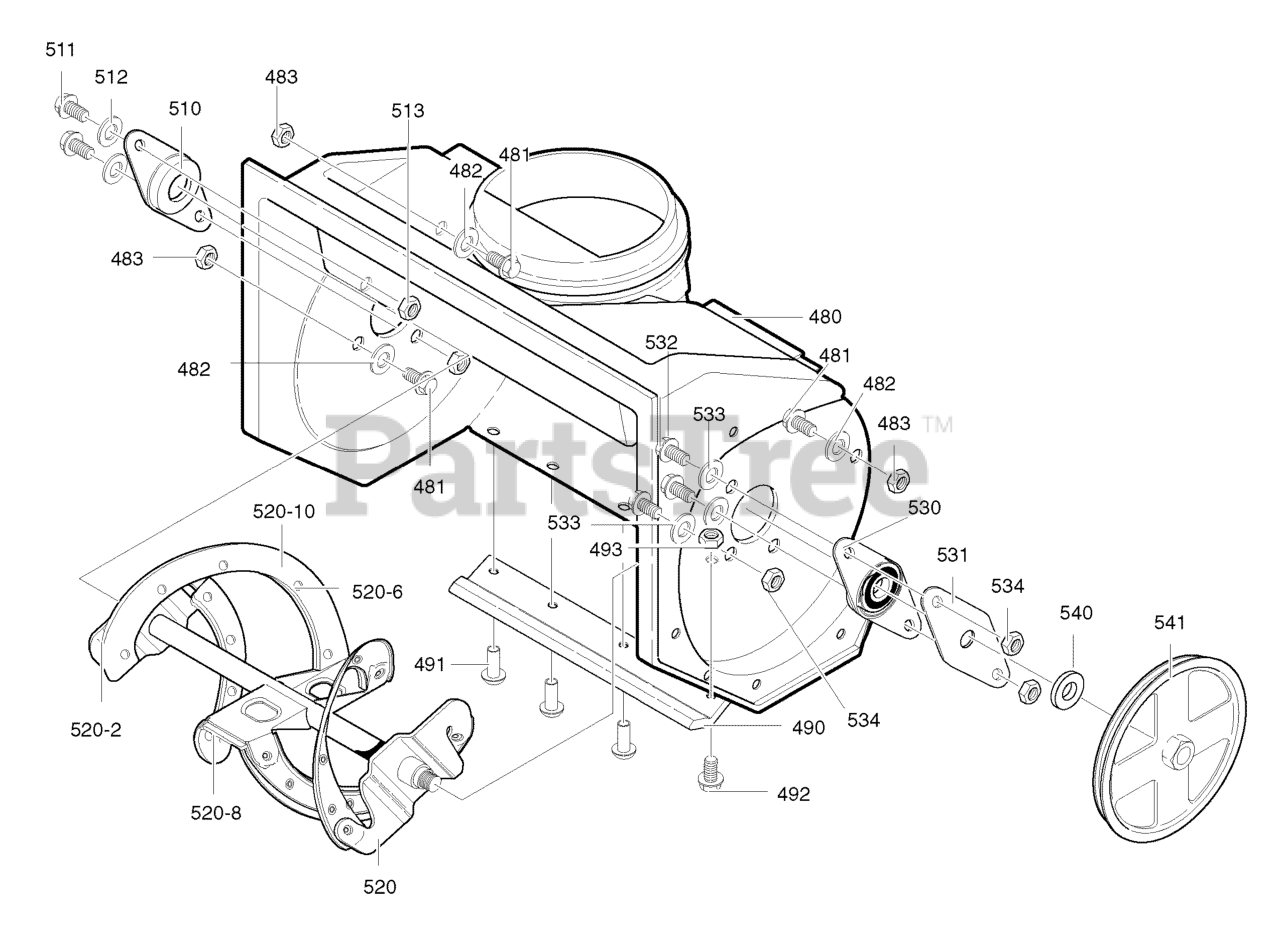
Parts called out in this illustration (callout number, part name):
480	HOUSING, ASSEMBLY
481	SCREW, 1/4-20 X .75
482	WASHER, FLAT .281 X .63 X .065
483	NUT, HEX 1/4-20 YZ
490	BLADE, SCRAPER
491	RIVET, OFFSET
492	SCREW, 1/4-20 X .75
493	NUT, 1/4-20 YZ
510	BEARING, FLANGE
511	SCREW, 1/4-20 X 1.00
512	WASHER, FLAT .281 X .63 X .065
513	NUT, 1/4-20
520	AUGER, ASSEMBLY
520-2	BLADE, AUGER
520-8	BLADE, CENTER
520-10	AUGER & BLADE SUPPORT
530	BEARING & PLATE ASSEMBLY
531	PLATE, RETAINER
532	SCREW, 1/4-20 X .63
533	WASHER, FLAT .281 X .63 X .065
534	NUT, 1/4-20
